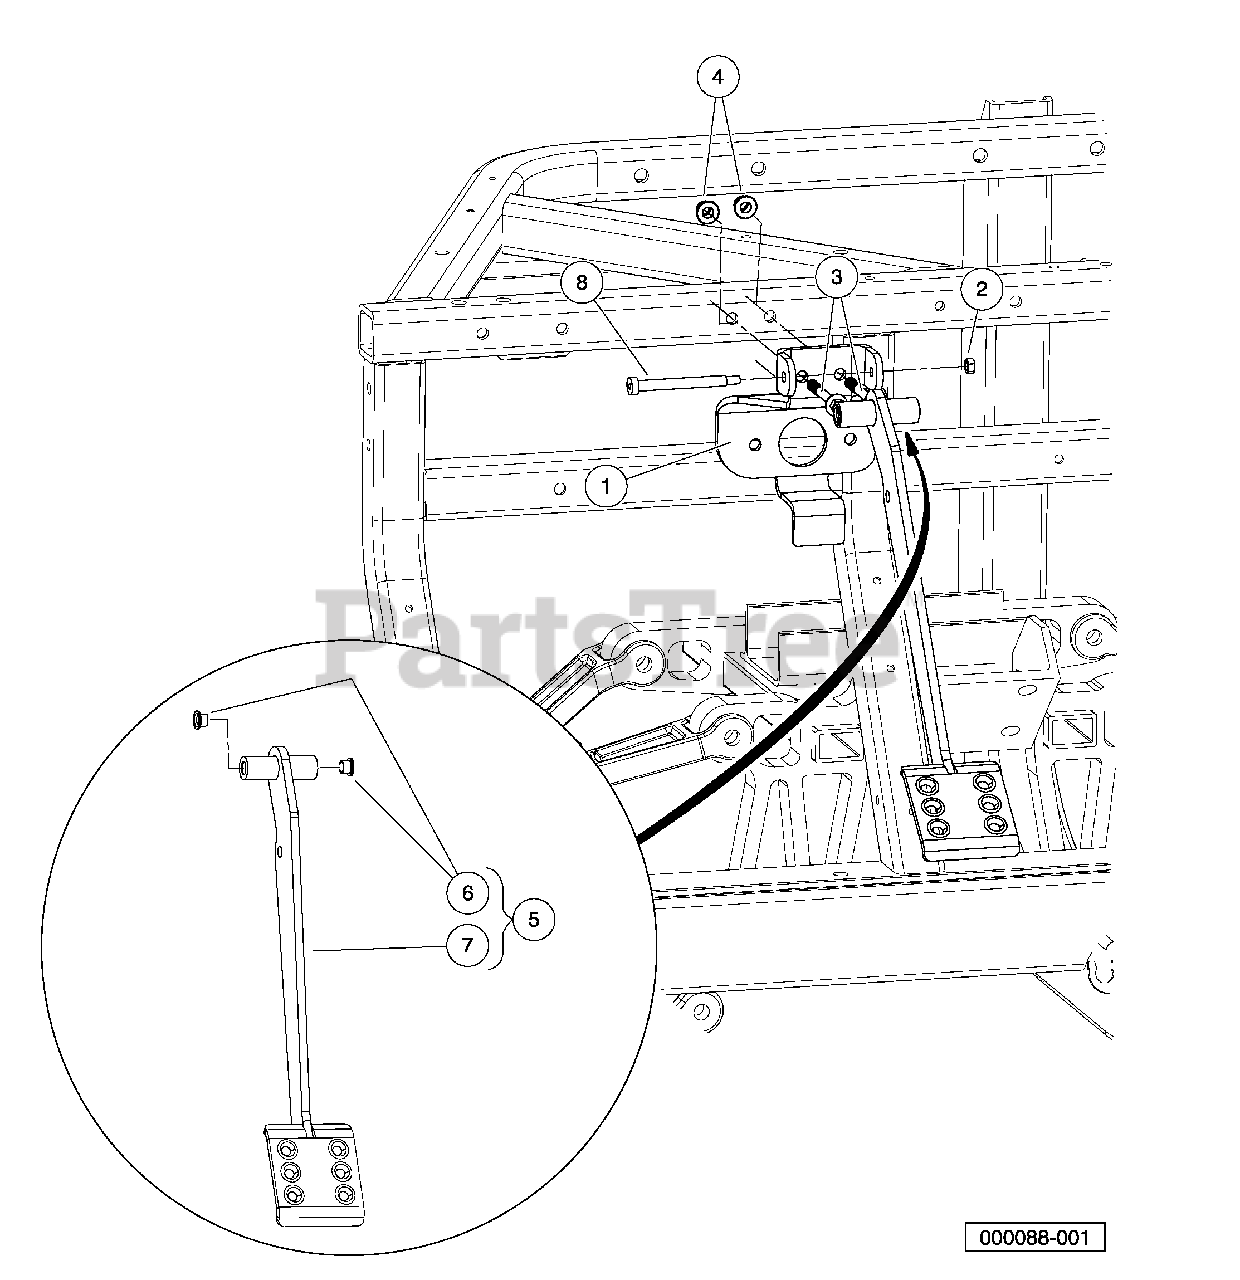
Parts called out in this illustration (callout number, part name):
1	Bracket, Pedal, Brake
2	Nut M6x1 Mech Def Center
3	Bolt Flanged Head, M8 X 1.25 X 65
4	Lock Nut, Flg M8 X 1.25 Nylon
5	Asm, Pedal, Brake, Hung
6	Bushing, Greaseless
7	Weldment, Pedal, Brake, Hung
8	Bolt, Shoulder, M8 X 70, Hc
